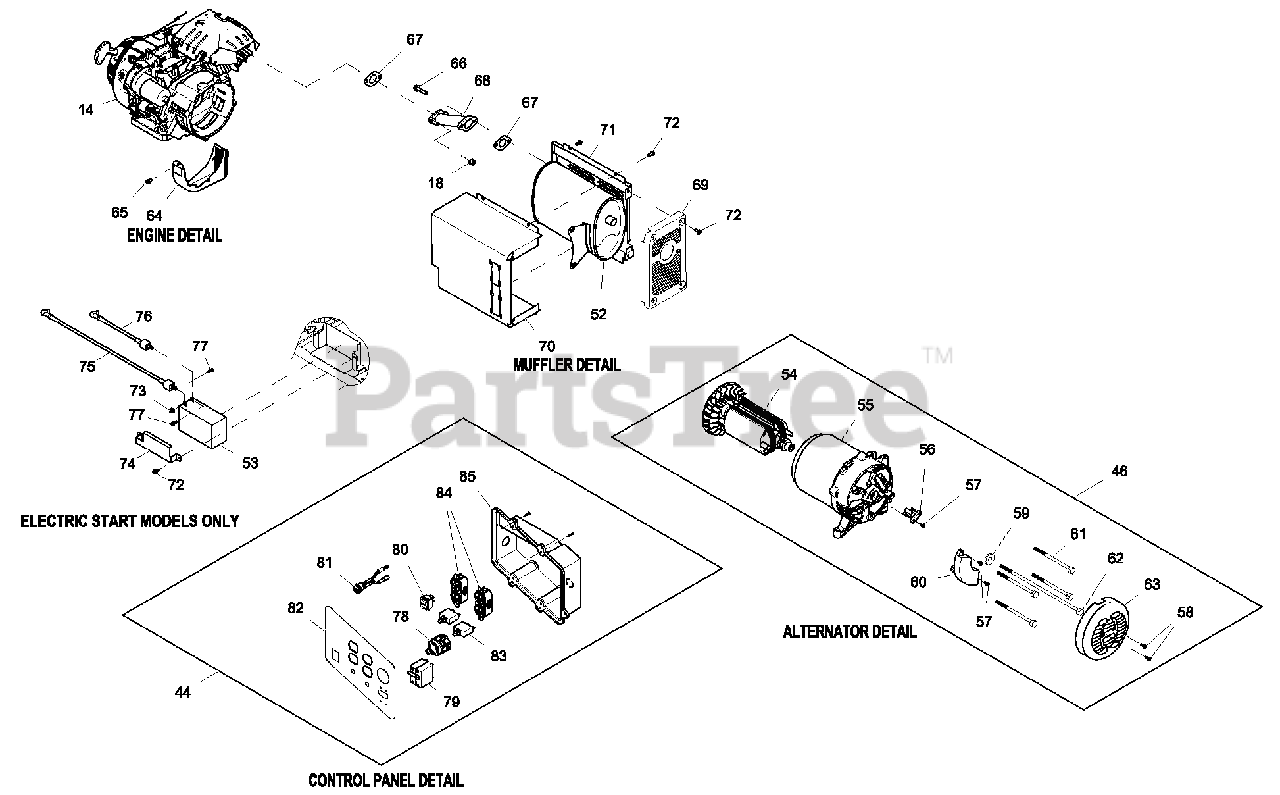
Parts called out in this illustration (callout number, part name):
52	MUFFLER HNYWL
53	BATTERY 12V10AH SEALED
56	ASSEMBLY,BRUSH
57	SCREW HHFC M5-0.8X12
58	SCREW HHFC M5-0.8X16
59	WASHER FLAT M10
60	AVR 5.5-7.5KW ALT
63	COVER ALTERNATOR INLET 5-7KW
64	SCROLL, HONEYWELL
65	SCREW HHC M5-0.8X10C8.8
66	SCREW HHFC M8-1.25 X 35 G8.8
67	GASKET, EXHAUST, 389CC
69	MUFFLER SHIELD FRONT HONEYWELL
70	MUFFLER SHIELD ALT SIDE HNYWL
71	MUFFLER SHIELD FRAME SIDE HW
72	SCREW HHFC M6-1.0X14
73	NUT FLANGE M5-0.8 NYLOCK
74	BRACKET BATTERY GP 5.5-7.5E
75	WIRE ASSY,BAH NEG.GRN
76	WIRE ASSY,BAH POS.RED
77	SCREW HHC M5-0.8 X12 C8.8
78	OUTLET 30A120/250V SPCGR
83	CB 20A1P 120V CUL/CSA JOEMEX
84	OUTLET 20A120V DPLX SPECGRADE
85	PANEL,CONTROL BACK BOX H PORT
